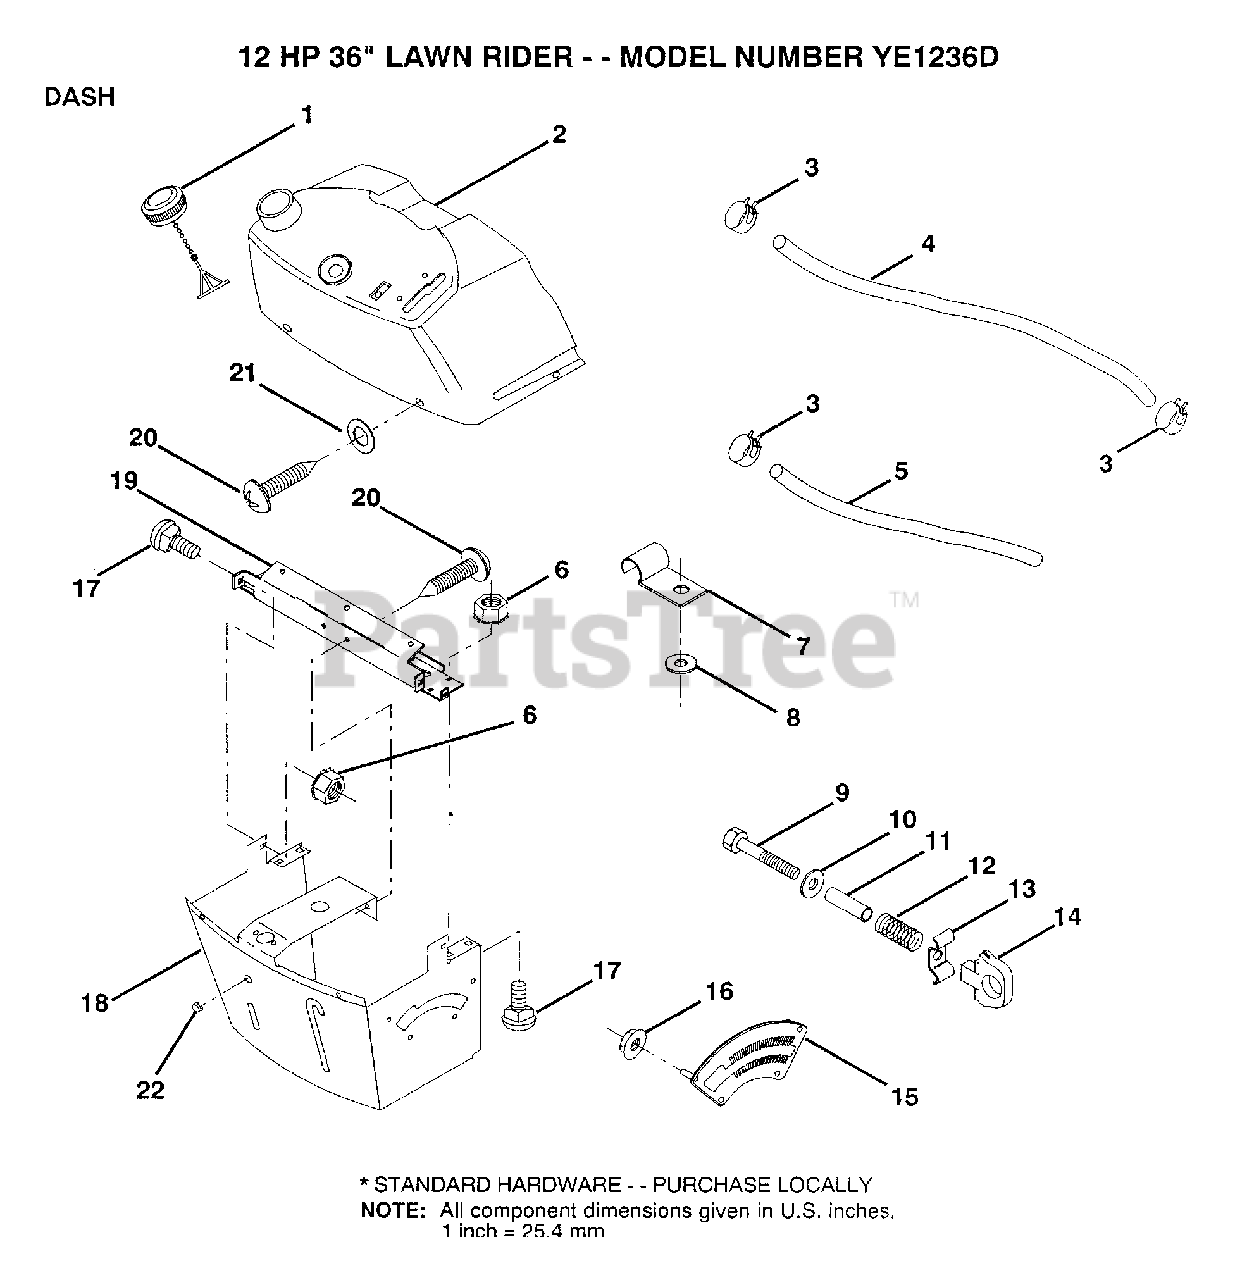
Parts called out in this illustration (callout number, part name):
3	HOSE CLAMP
5	FUEL LINE T
6	NUT
7	CLIP T
8	WASHER PM
9	BOLT
11	SPACER SPLIT
12	SPRING M
13	"KNOB,HGT RETAINER"
14	KNOB
15	ADJUSTER QUAD
16	NUT
17	BOLT
18	SUPT ASSY DASH
19	CROSS BRACE
22	PLUG DOME
